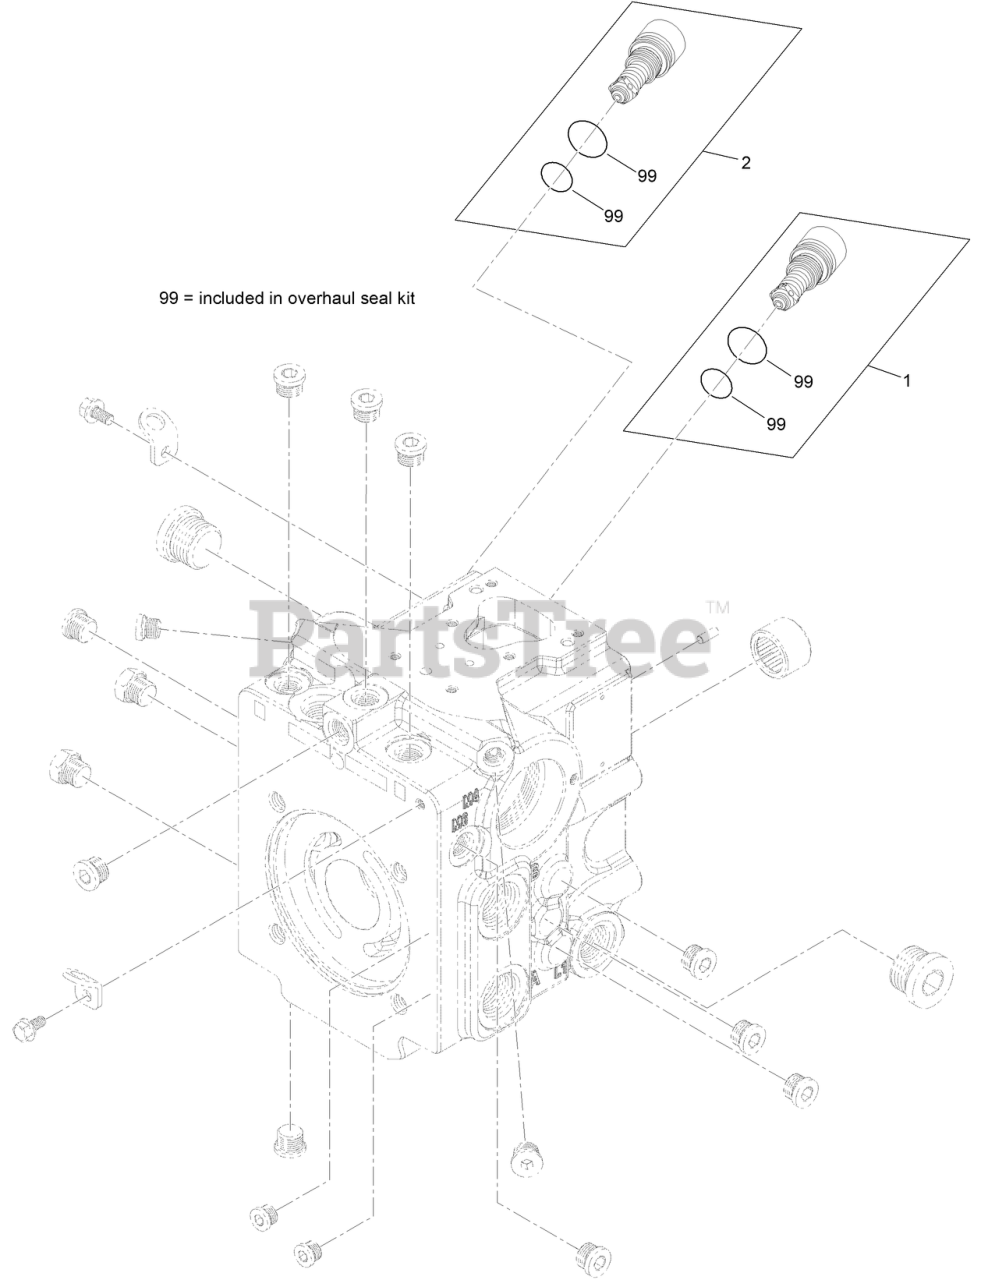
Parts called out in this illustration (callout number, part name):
1	VALVE-RELIEF, HIGH PRESSURE
2	VALVE-RELIEF, HIGH PRESSURE
99	SEAL KIT
